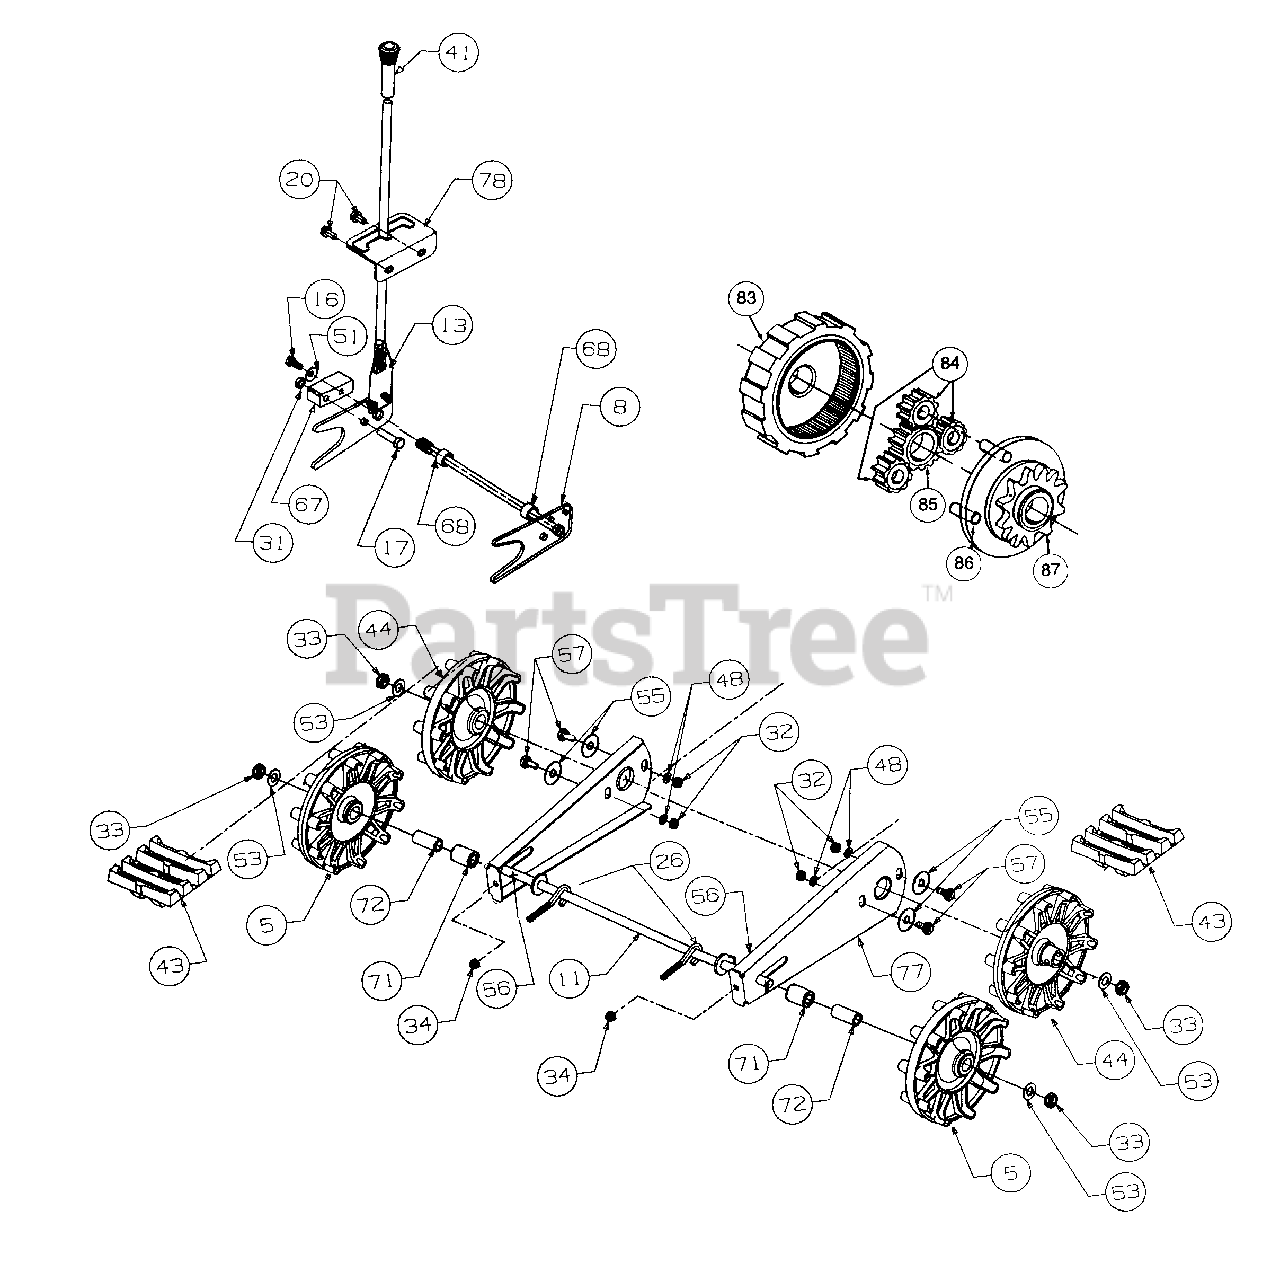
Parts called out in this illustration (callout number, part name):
5	Wheel Assembly Idler
16	Screw
17	Screw
20	Screw
26	Screw
31	Nut Lock
32	Nut Hex
33	Nut Jam
34	Nut Hex
43	Track
44	Wheel-Track Drive
48	Washer-Lock
51	Washer-Bell
53	Washer-Flat
55	Washer-Flat
56	Lubricant
57	Screw-Shoulder
67	Lift-Shaft Drive
68	Spacer
71	Spacer
72	Spacer
83	Gear Ring
84	Gear 12-Tooth
85	Gear 18-Tooth
86	Pin Dowel
87	Carrier
